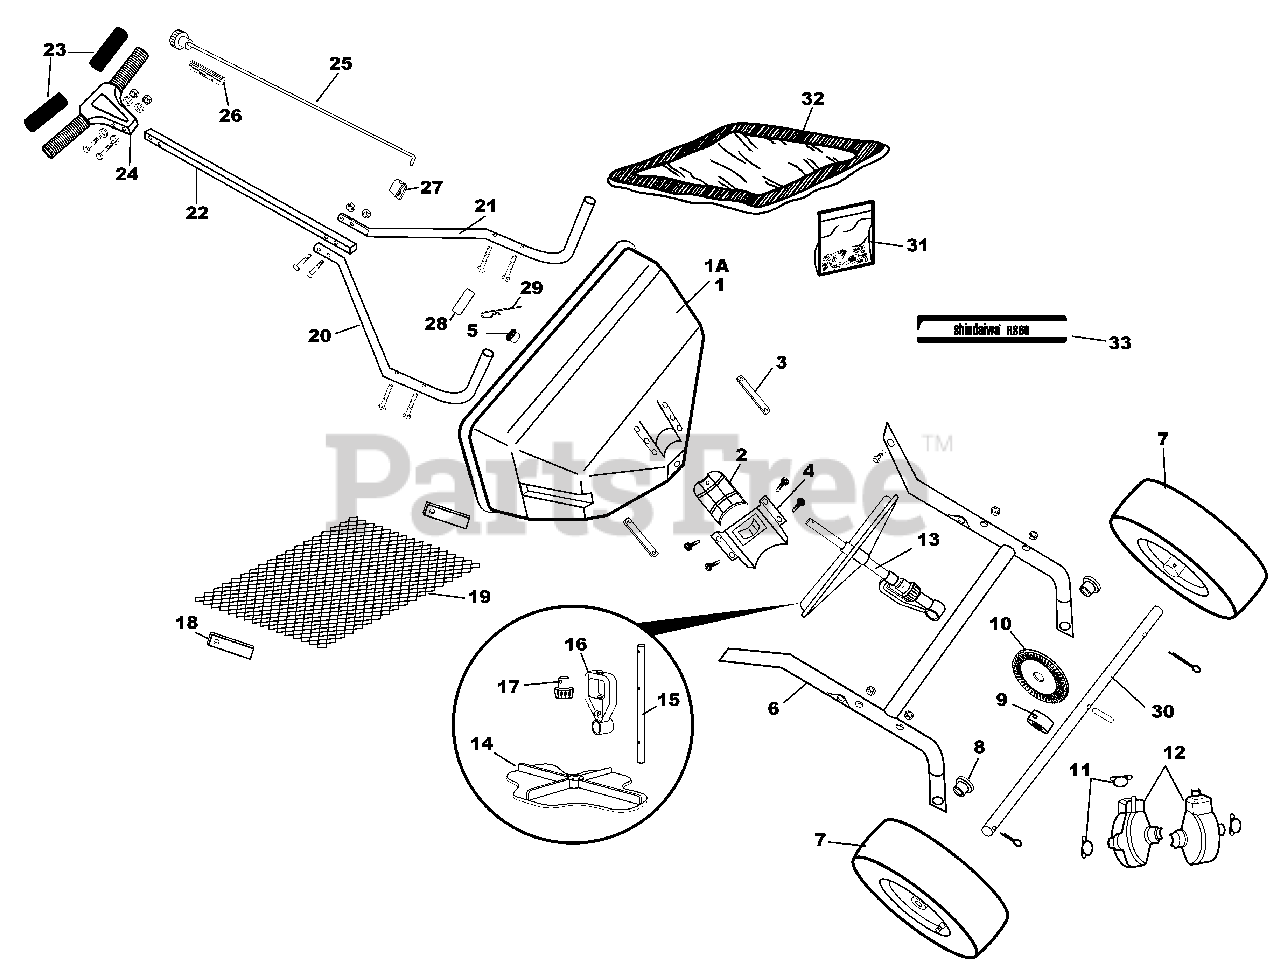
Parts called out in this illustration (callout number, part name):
1	Hopper Assembly
1A	Hopper
2	Shutoff Plate
3	Shutoff Plate Guides
4	Rate Cam & Chute Assembly
5	Impeller Shaft Bearing
6	Frame Assembly
7	Drive & Free Turning Wheel
8	Axle Bushings
9	Axle Collar
10	Axle Gear
11	Gear Cover Clamps
12	Gear Cover
14	Impeller
15	Impeller Shaft
16	Gear Support
17	Pinion Gear
18	Screen Clips
19	Hopper Screen
20	Handle Brace W/ Plug– LH.
21	Handle Brace W/ Plug– RH.
22	Handle Tube
23	Handle Grips
24	T-Handle Assembly
25	Control Knob & Wire Ass’y.
26	Control Knob Spring
27	Wire Retaining Clip
28	Hopper Plug
29	Agitator
30	Impeller Assembly
31	Parts Package
32	Hopper Cover
33	Hopper Label
